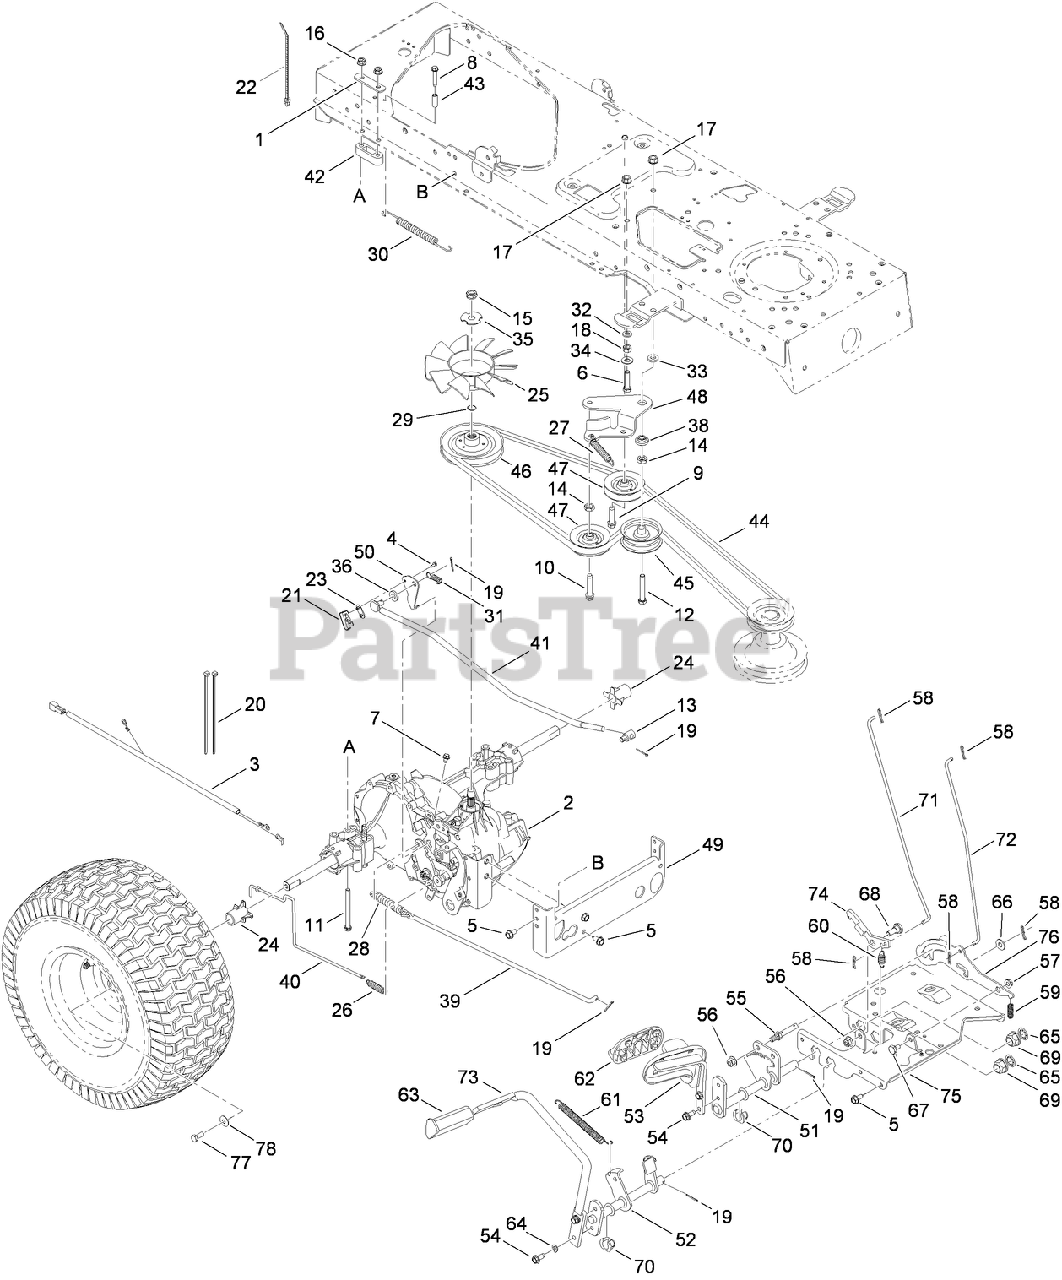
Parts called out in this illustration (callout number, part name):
1	BRACKET-MOUNTING, TRANSMISSION
2	HYDRO TRANSMISSION ASM
3	BRACKET-PIVOT, SUPPORT
4	FAN-BLADE, 10
5	SCREW-TAP
6	SCREW-HH
7	SCREW-TAP
8	SCREW-HWH
9	SCREW-TAP
10	SCREW-TAP
11	SCREW-HH
12	SCREW-HH
13	FERRULE
14	NUT-JAM
15	NUT-JAM
16	NUT-LOCK, FLANGE
17	NUT-LOCK, FLANGE
18	NUT-LOCK, FLANGE
19	PIN-COTTER
20	TIE-CABLE
21	SWITCH-SPRING, SHORT
22	TIE-CABLE
23	PLATE-INSULATOR
24	SLEEVE
26	SPRING-EXTENSION
27	SPRING-EXTENSION
28	SPRING-EXTENSION
29	RING-WIRE
30	SPRING-EXTENSION
31	SPRING-EXTENSION
32	WASHER-LOCK
33	WASHER-FLAT
34	WASHER-FLAT
35	WASHER-LOCK
36	WASHER-FLAT
38	SPACER-SHOULDER
39	ROD-BRAKE
40	ROD-HYDRO
41	ROD-CONTROL
42	SPACER-TRANSAXLE
43	SPACER
44	BELT-V
45	PULLEY-IDLER, FLAT
46	PULLEY-INPUT
47	PULLEY-IDLER, Y TYPE
48	BRACKET-IDLER, CENTER DOUBLE
49	BRACKET-TORQ, TRANSMISSION
50	BRACKET-ACTUATOR
51	CONTROL ASM
52	SPEED CONTROL ASM
53	CONTROL PEDAL ASM
54	SCREW-HWH
56	NUT-LOCK, FLANGE
57	NUT-LOCK, FLANGE
58	PIN-COTTER
59	SPRING
60	SPRING-EXTENSION
61	SPRING-EXTENSION
62	PAD-PEDAL
63	PAD-BRAKE
64	WASHER-LOCK
65	WASHER-FLAT
66	WASHER-FLAT
67	BOLT-SHOULDER
68	BOLT-SHOULDER
69	BEARING-FLANGE
70	BEARING-FLANGE, HEX (SPLIT)
71	ROD-BRAKE, LOCK
72	ROD-CONTROL, CRUISE
73	PEDAL-BRAKE
74	LATCH-CRUISE
75	BRACKET-SUPPORT, STEERING
76	BRACKET-LOCKOUT
77	SCREW-HH
78	WASHER-BELL
